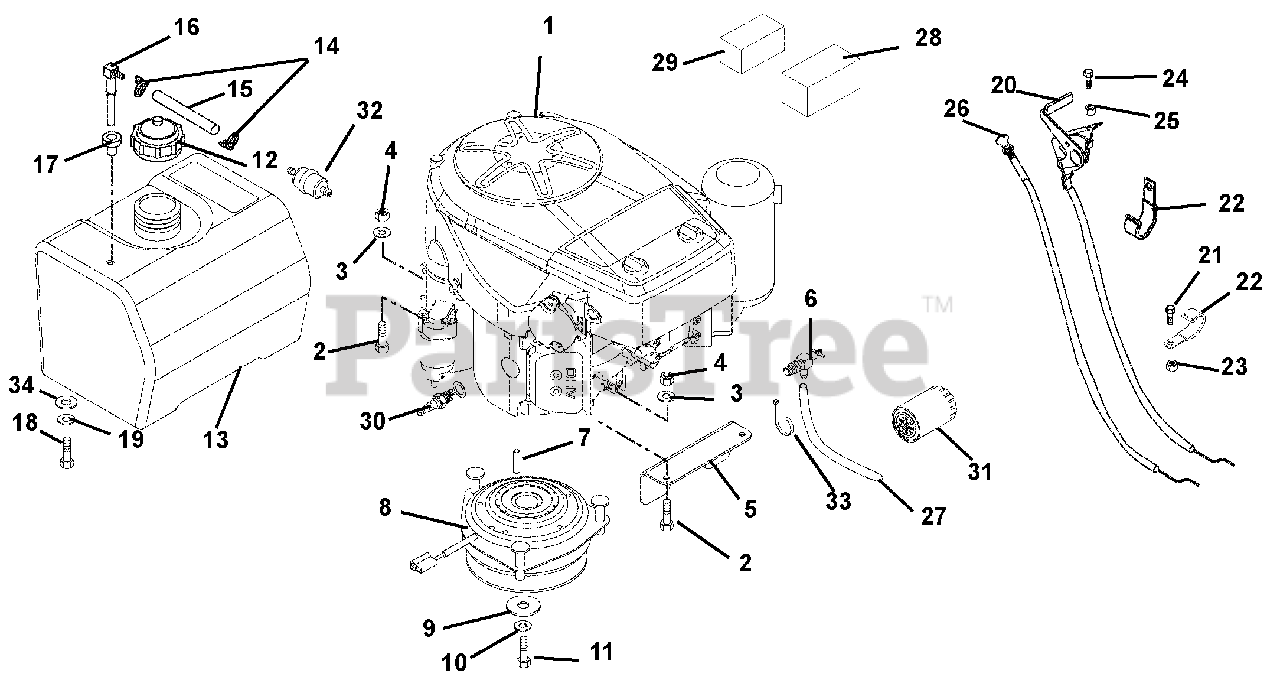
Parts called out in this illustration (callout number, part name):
1	Engine, 15 HP Kawasaki (105, 106, 120)
2	Bolt-Hex .31-18 x 1.75 Grade 5
3	Washer-Locking .31 x .078 Regular
4	Nut-Hex .31-18
5	Bracket, Clutch
6	Valve, Oil Drain
7	Key-Square .25 x 1.25 x 25 SAE 8630 OR SAE 1035
8	Clutch, Electric
9	Washer-Flat-Steel .469 x 2.00 x .25
10	Washer-Locking .44 x .109 Regular
11	Bolt-Hex .44-20 x 3.00 Grade 5
12	Cap, Fuel
13	Tank, Fuel
14	Clamp-Hose Wire .49/.51 x .116
15	Gas Line-Bulk .25 I.D.
16	Fitting, Tank
17	Bushing (Black in color. Does not replace or interchange with orange colored grommet.)
18	Bolt-Hex .38-16 x .75 Grade 5
19	Washer-Locking .38 x .094 Regular
20	Cable, Throttle-with Liner (105,106, 108, 109)
21	Bolt-Hex .31-18 x .75 Grade 5
22	J-Clamp
23	Nut-Locking-Nylon .312-18
24	Screw-Machine 10-24 x .75 Hex Washer Head
25	Nut-Locking-Nylon 10-24 with Insert
26	Control, Choke
27	Tube, Oil Drain
28	Filter, Air Paper (105, 106, 120)
29	Filter, Air Foam (105, 106, 120)
30	Spark Plug
31	Filter, Oil
32	Fuel Filter- Kawasaki
33	Cable Tie
34	Washer, Flat Steel .409 x .812 x .065
